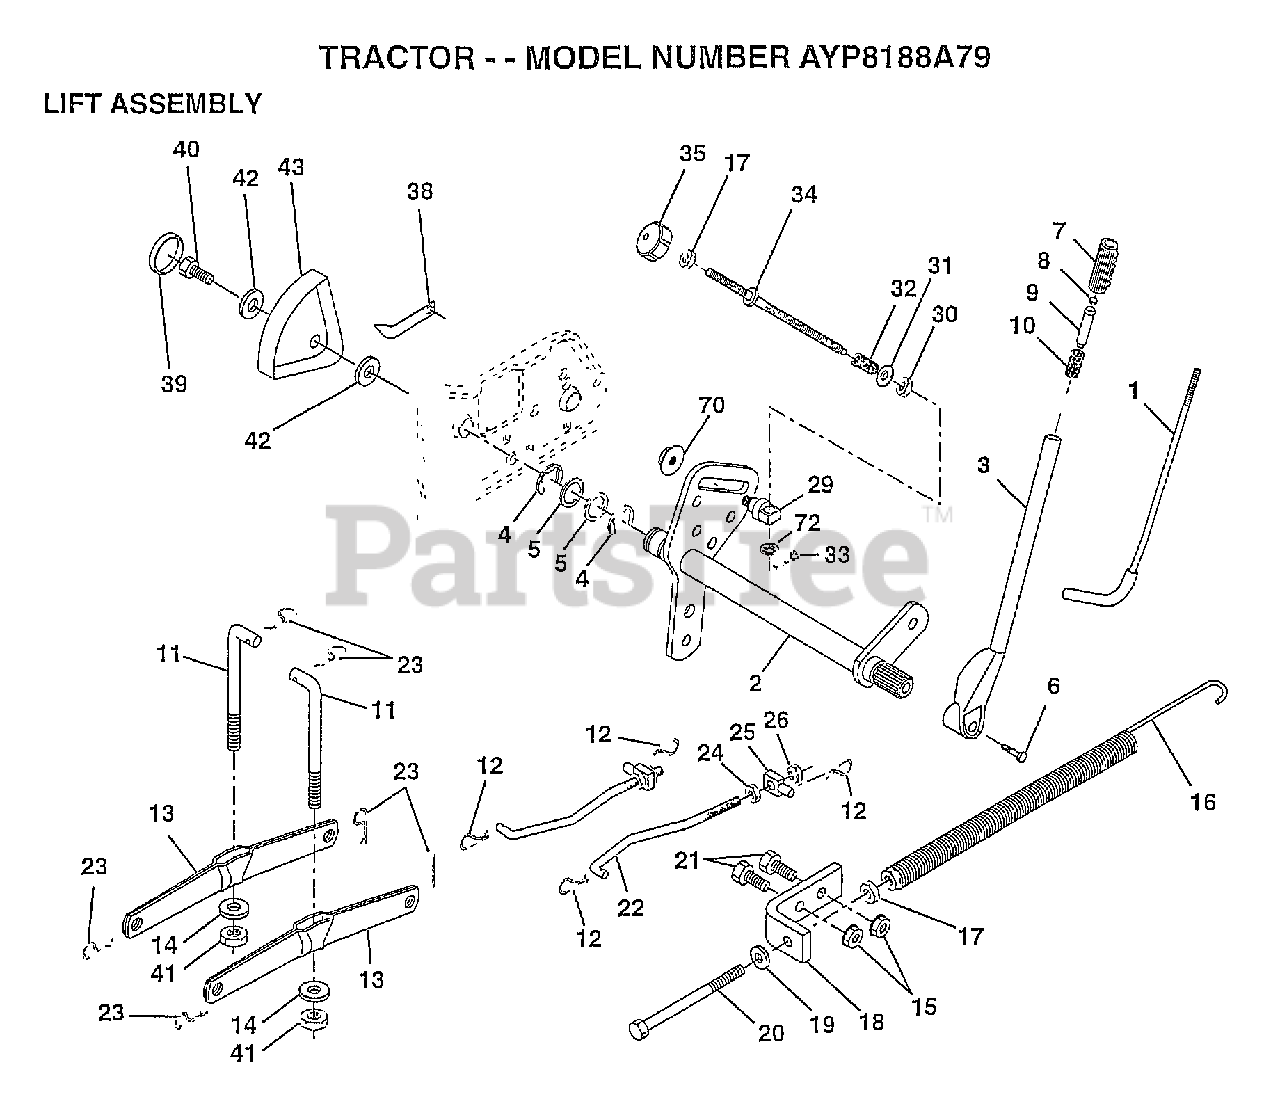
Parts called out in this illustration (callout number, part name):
1	LEVER ROD LT
2	SHAFT AMS LIFT
4	E-RING
5	WASHER
6	"BOLT,HEX"
7	GRIP HANDLE
10	SPRING T
11	LINK.LIFT.MWR.VGT
12	RETAINER.SPRING
13	ARM SUSP REAR
14	BEARING PVT LH
17	NUT
18	BRACKET SPRING AS
19	WASHER
20	BOLT-ADJ SPRING T
21	BOLT
22	LINK.FRONT
24	NUT
25	TRUNION
26	NUT.LK.W/WSH.1/2.
29	TRUNNION
30	NUT T
31	WASHER
32	SPRING.COMP.INF.H
34	ROD.ADJ.LIFT
35	KNOB INF 3/8-16
38	POINTER-INDICAT
39	"PLUG,HOLE"
40	SCREW
41	NUT.CROWNLOCK.3/8
42	WASHER
43	HEIGHT INDICATOR
70	NUT.HXFLG.LOCK.
72	NUT PUSH M
